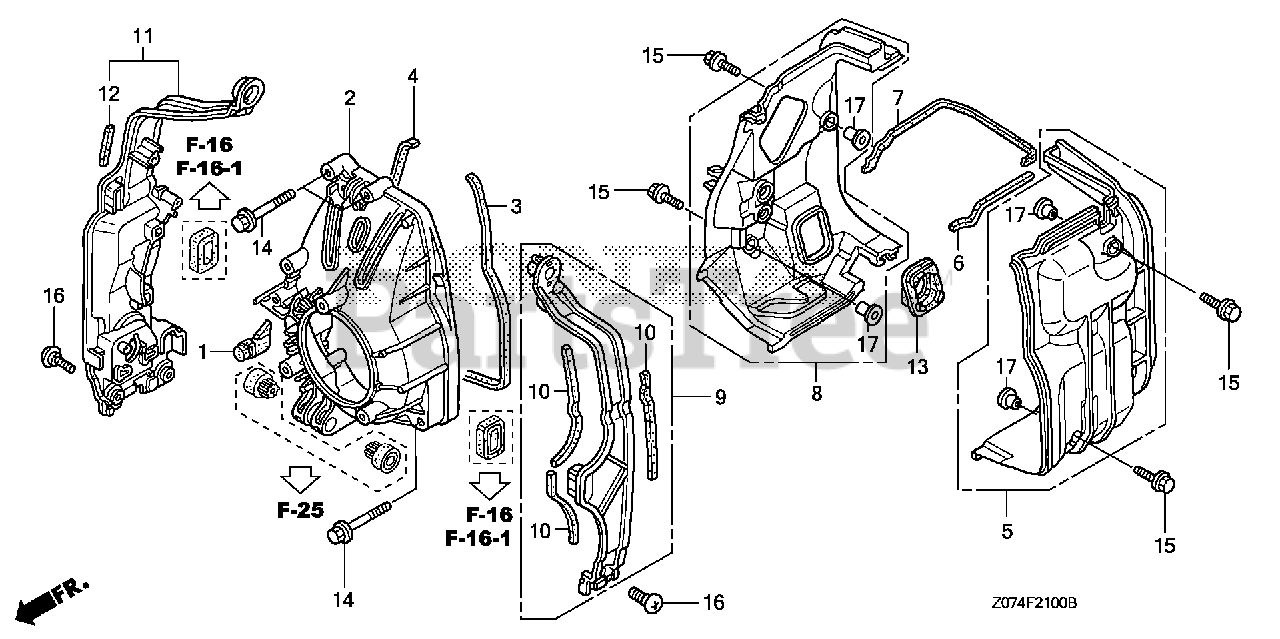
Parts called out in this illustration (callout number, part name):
1	RUBBER, TANK PROTECTOR
2	COVER, FAN
3	SEAL, R. FAN COVER (L. SIDE)
4	SEAL, L. FAN COVER (R. SIDE)
5	SHROUD, R. (L. SIDE)
6	SEAL, R. SHROUD (UPPER) (L. SIDE)
7	SEAL, L. SHROUD (UPPER) (R. SIDE)
8	SHROUD, L. (R. SIDE)
9	FRAME ASSY., R. FR. (L. SIDE)
10	SEAL, R. FR. FRAME (L. SIDE)
11	FRAME ASSY., L. FR. (R. SIDE)
12	SEAL, L. FR. FRAME (R. SIDE)
13	RUBBER, OIL CHECK
14	BOLT, FLANGE (6X45)
15	BOLT, FLANGE (6X23)
16	SCREW, SPECIAL (6X15)
17	COLLAR, FAN COVER (Honda Code 5580527). (N/A: SEE ASSEMBLY)
